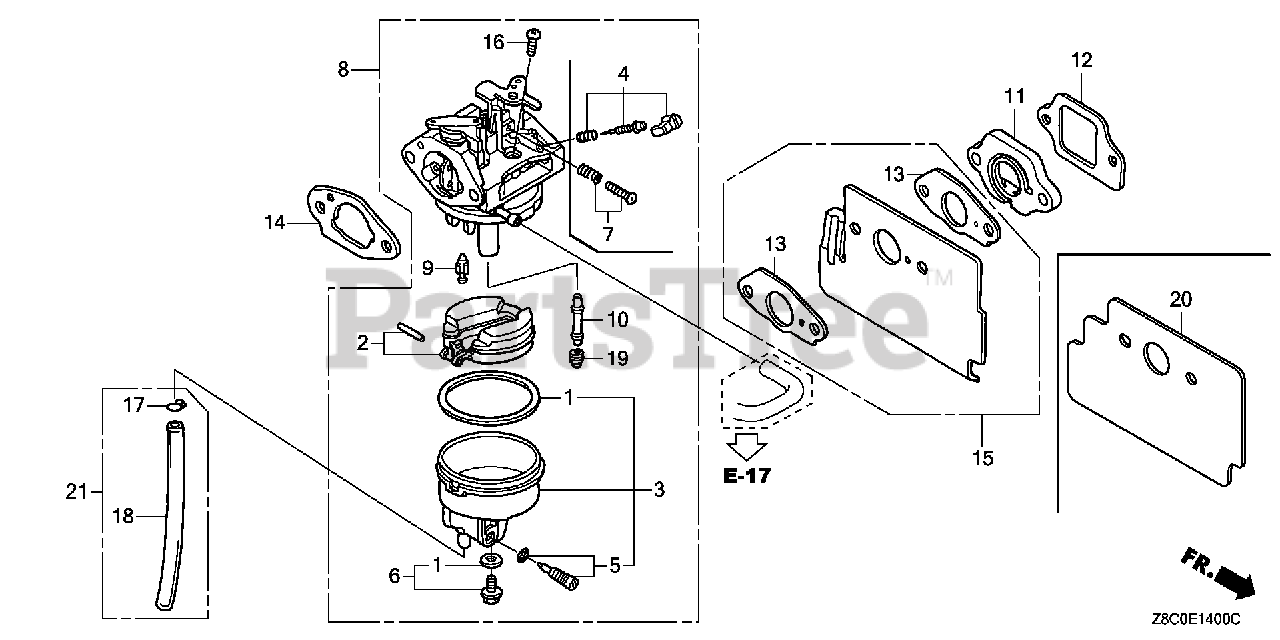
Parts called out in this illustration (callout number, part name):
1	GASKET SET
2	FLOAT SET
3	CHAMBER SET, FLOAT
4	SCREW SET (CARBURETOR NO.)
5	SCREW SET, DRAIN (ADVENTURE GREEN) (CARBURETOR NO.)
6	SCREW SET B
6	SCREW SET
7	SCREW SET (THROTTLE STOP) (CARBURETOR NO.)
8	CARBURETOR ASSY. (BB61U A)
9	VALVE, FLOAT (CARBURETOR NO.)
10	NOZZLE, MAIN (CARBURETOR NO.)
11	INSULATOR, CARBURETOR
12	GASKET, INSULATOR
14	GASKET, CARBURETOR (Honda Code 5580253). (CHOKE SIDE)
16	SCREW, PAN (5X6)
17	CLIP, TUBE (B6.5)
19	JET, MAIN (#65) Use up to Engine SN BB30A D.
19	JET, MAIN (#70) Use up to Engine SN BB30A D.
19	JET, MAIN (#72) Use from Engine SN 6185281.
20	GUIDE, AIR
21	TUBE ASSY., DRAIN
